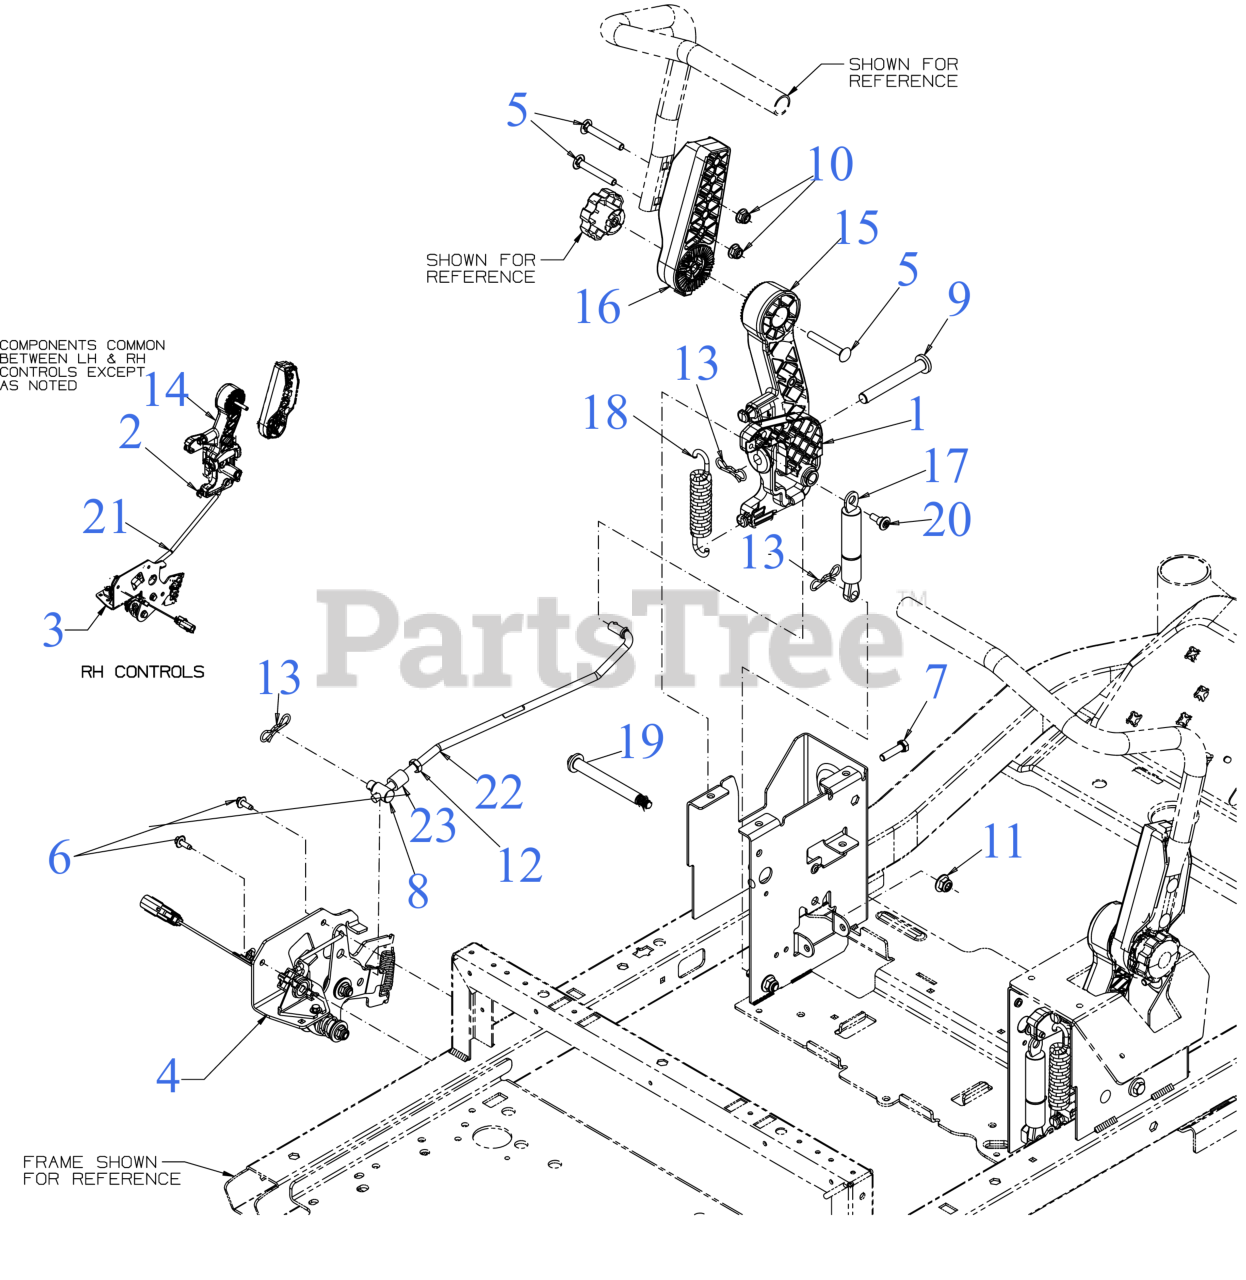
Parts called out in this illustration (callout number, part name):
1	CONTROL ACTUATOR (LH)
2	CONTROL ACTUATOR (RH)
3	LAPBAR CONTROL (RH)
4	LAPBAR CONTROL (LH)
5	BOLT 5/16-18 x 2.50 GR1
6	SCREW M6-1 x .625
7	SCREW 5/16-18 x 1.25 GR5
8	CONTROL ROD FERRULE
9	CLEVIS PIN
10	FLANGE LOCK NUT 5/16-18
12	HEX JAM NUT 3/8X24
13	BOW TIE COTTER PIN
14	LAPBAR ACTUATOR (RH)
15	LAPBAR ACTUATOR (LH)
16	UPPER ADJUSTMENT HANDLE
17	DAMPNER CYLINDER
18	EXTENSION SPRING .57 x 5.38
19	SHOULDER SCREW .491x3.937 3/8-16
20	SHOULDER SCREW .394X.280:1/4-14
21	CONTROL ROD (RH)
22	CONTROL ROD (LH)
23	SPACER-.375X.625X.600
